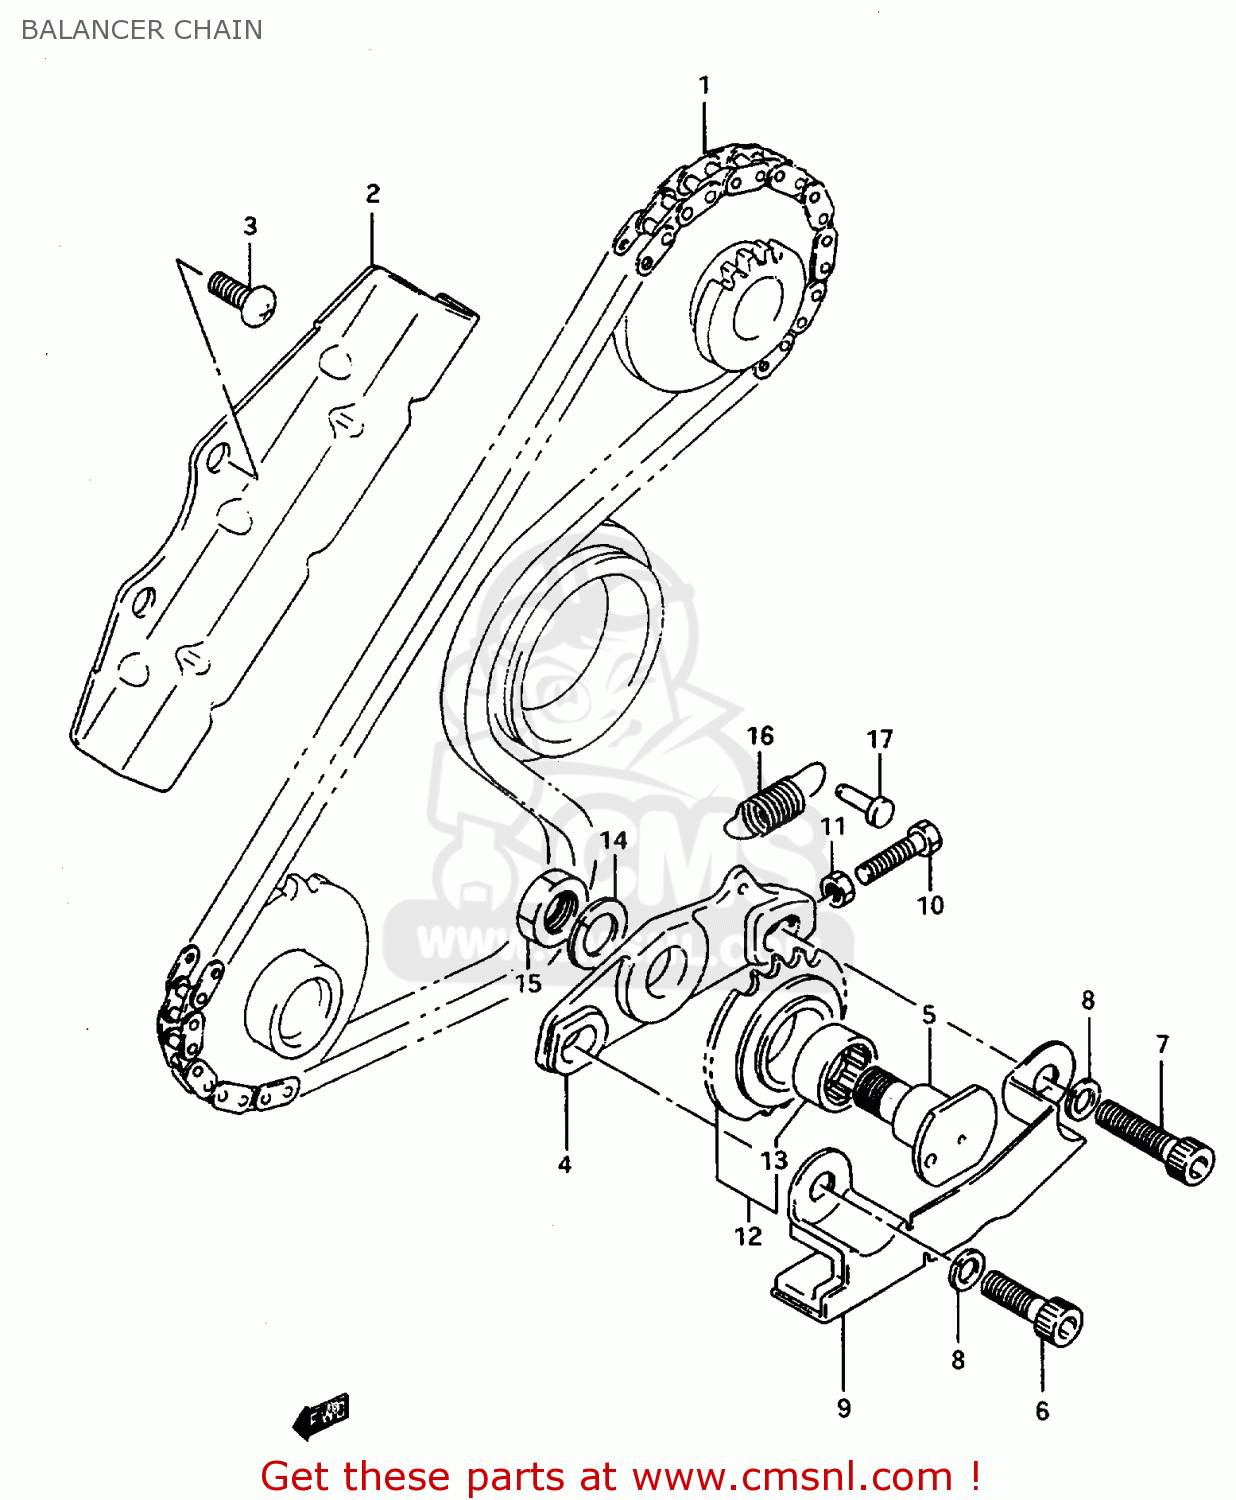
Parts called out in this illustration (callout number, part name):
1	CHAIN,BALANCER
2	GUIDE,BALANCER CHAIN
3	SCREW
4	BRACKET, CHAIN TENSIONER
5	SHAFT,BALANCER CHAIN TENSIONER
6	BOLT(8X22)
7	BOLT
8	LOCK WASHER
9	GUIDE, CHAIN TENSIONER
10	BOLT
11	NUT
12	SPRKT,BALANCER CHAIN TENSIONER
13	BEARING(17X23X12)
14	WASHER,LOCK
15	NUT
16	SPRING
17	RIVET
